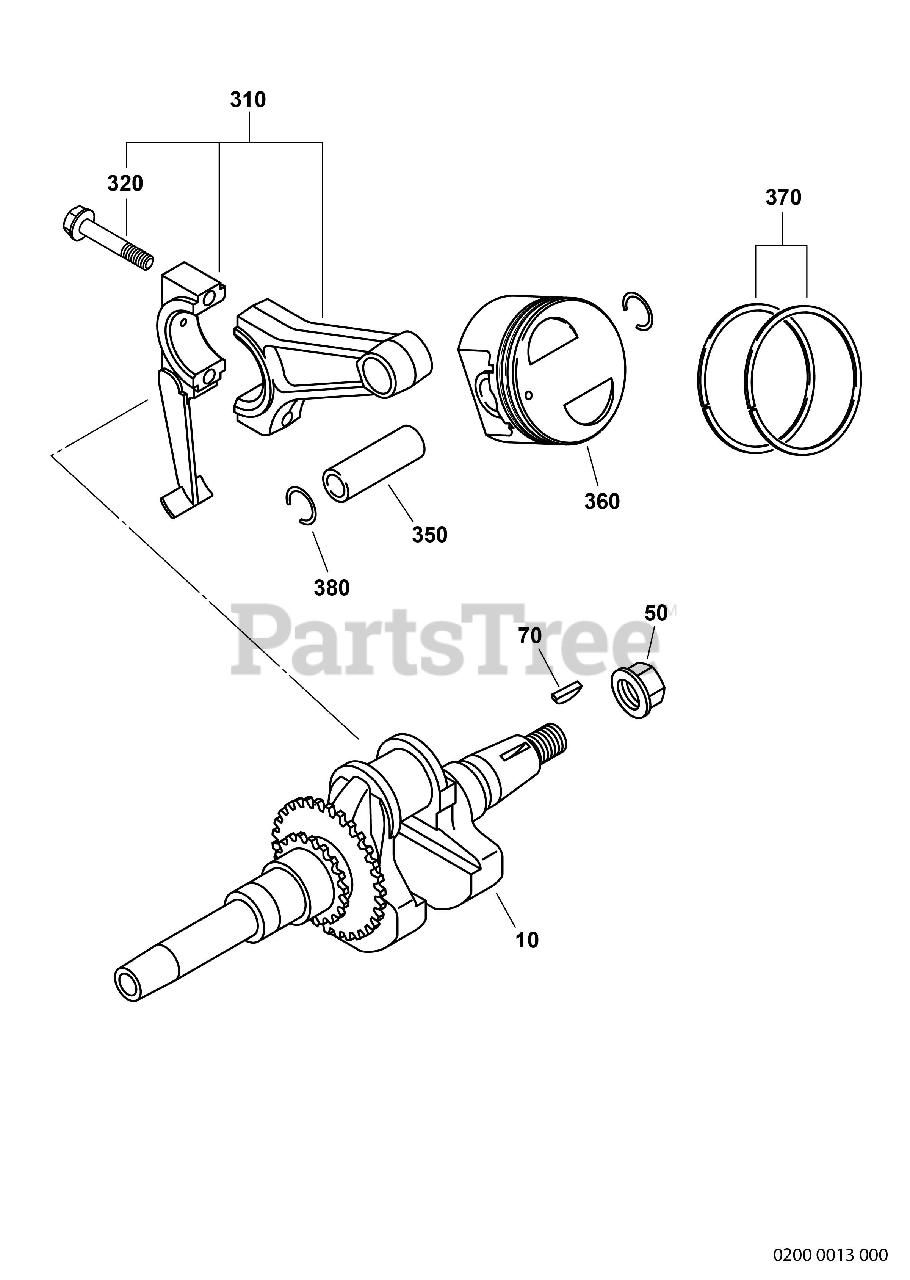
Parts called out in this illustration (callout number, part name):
10	CRANK SHAFT CP
310	CONNECTING ROD AY
370	PISTON RING SET
